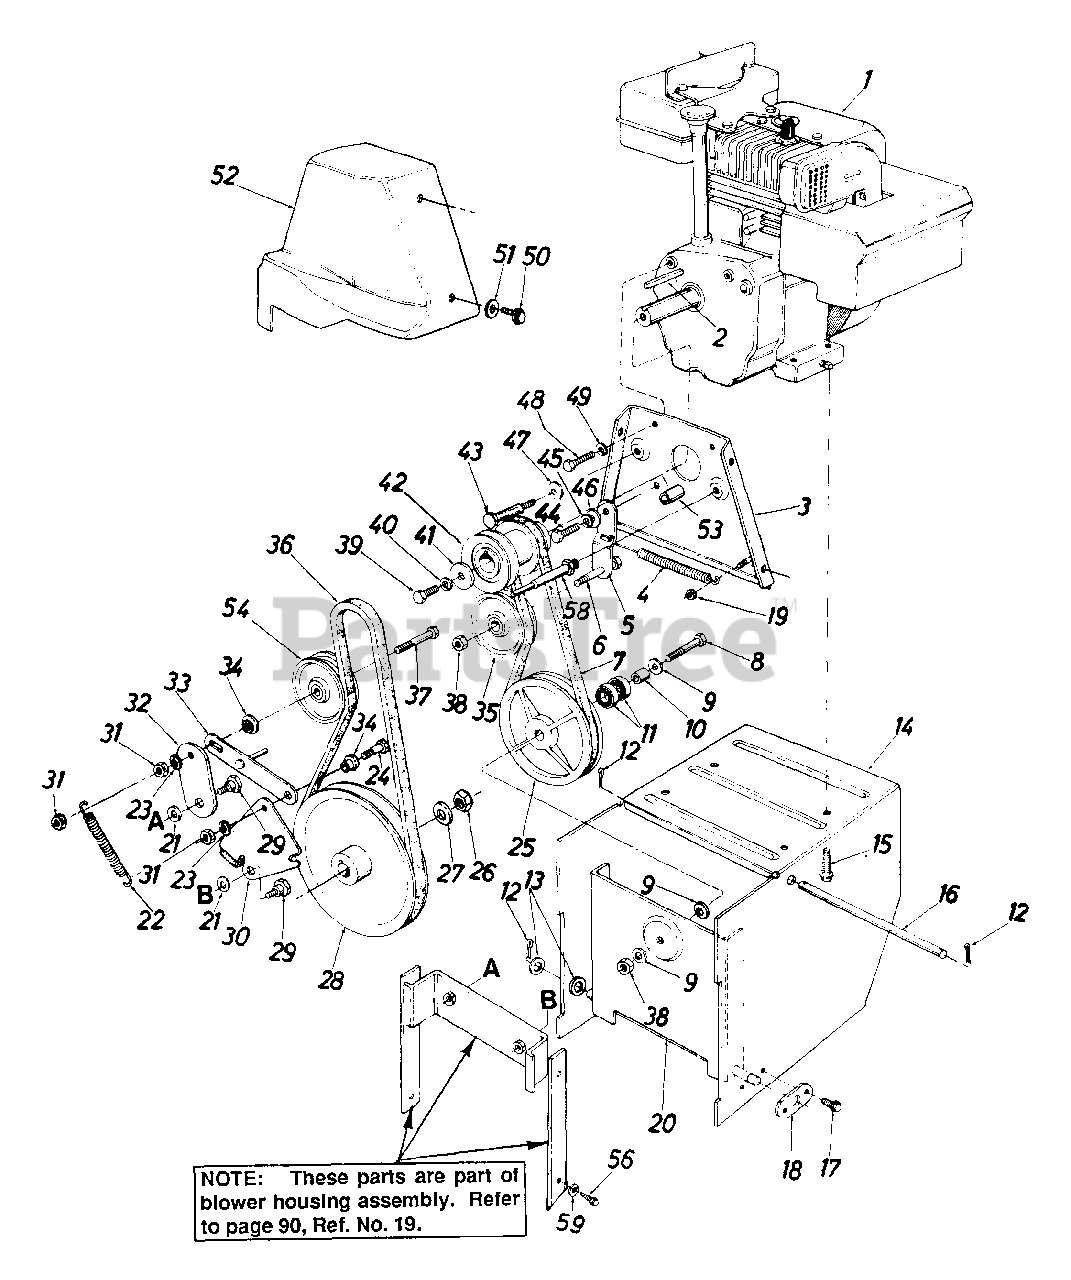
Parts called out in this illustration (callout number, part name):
1	Engine
2	Sq. Key 3/16" x 1.50" Lg.
2	Sq. Key 1/4" x 2.0" Lg.
3	Engine Plate Ass'y.
4	Extension Spring .50" O.D. x 3.97" Lg.
5	Drive Clutch Idler Brkt.
6	Hex Bolt 3/8-24 x 1.25" Lg.
7	V-Belt
8	Hex Bolt 3/8-24 x 1.50" Lg.
9	Bell-Wash. .40" I.D. x .88" O.D. x .06
10	Spacer .38" I.D. x .62" O.D. x .75" Lg.
11	Ball Brg. .62" I.D. x 1.38" O.D. x .44
12	Cotter Pin 3/32" Dia. x .75" Lg.
13	Fl-Wash. .53" I.D. x 1.00" O.D. x .125
14	Frame Ass'y.
15	Hex Wash. Hd. Self-Tap Scr. 3/8-16 x 1.25" Lg.
16	Shaft .50" Dia. x 9.50" Lg.
17	Hex Wash. Hd. Self-Tap Scr. 1/4-20 x .50" Lg.
18	Axle Bracket
19	Hex L-Nut 1/4-20 Thd.
20	Drive Pulley Support Brkt. Ass'y.
21	Bell-Wash. .40" I.D. x 1.13" O.D.
22	Extension Spring .56" O.D. x 4" Lg.
23	L-Wash. 3/8" I.D.
24	Hex Scr. 3/8-16 x 1.25" Lg.
25	6.00" O.D. Drive Pulley Ass'y.
26	Hex Jam Cent. L-Nut 5/8-18 Thd.
27	Fl-Wash. .64" I.D. x .94" O.D. x .06
28	1/2" V-Pulley .625" I.D. x 7.50" O.D.
28	5/8" V-Pulley .625" I.D. x 7.50" O.D.
29	Shld. Bolt .625" Dia. x .170" Lg. (3/8-16)
30	Brake Bracket Ass'y.
30	Brake Brkt. Ass'y.
31	Hex Ins. L-Nut 3/8-16 Thd.
32	Auger Clutch Idler Brkt.
33	Brake Linkage Ass'y.
34	Shld. Spacer .625" I.D.
35	Fl-Idler Pulley 2.25" O.D.
36	V-Belt
37	Hex Bolt 3/8-16 x 2" Lg.
38	Hex Ins. Jam L-Nut 3/8-24 Thd.
39	Hex Bolt 3/8-24 x 1.50" Lg.
40	L-Wash. 3/8" I.D.
41	Bell-Wash. .40" I.D. x 1.25" O.D.
41	Bell-Wash. .345" I.D. x .88" O.D.
42	Double Groove Engine Pulley
43	Shld. Scr. .498" x 3.0" Lg.
43	Stud 3/8-16 x 3.37" Lg.
44	Hex Bolt 5/16-24 x 1.00" Lg.
45	L-Wash. 5/16" I.D.
46	Shld. Spacer .27" Lg.
47	Bell-Wash. .40" I.D. x .88" x .06
48	Hex Bolt 5/16-24 x .62" Lg.
49	L-Wash. 5/16" I.D.
50	Hex Wash. Hd. Self-Tap Scr. 1/4-20 x .50" Lg.
51	Fl-Wash. .28" I.D. x .75" O.D. x .06
52	Belt Cover
53	Spacer
54	Fl-Idler Pulley 2.75" O.D.
56	Hex Wash. Hd. Self-Tap Scr. 3/8-16 x .75" Lg.
58	Stud 3/8-16 x 3.37" Lg.
59	L-Wash. 3/8" I.D. - H.D.
